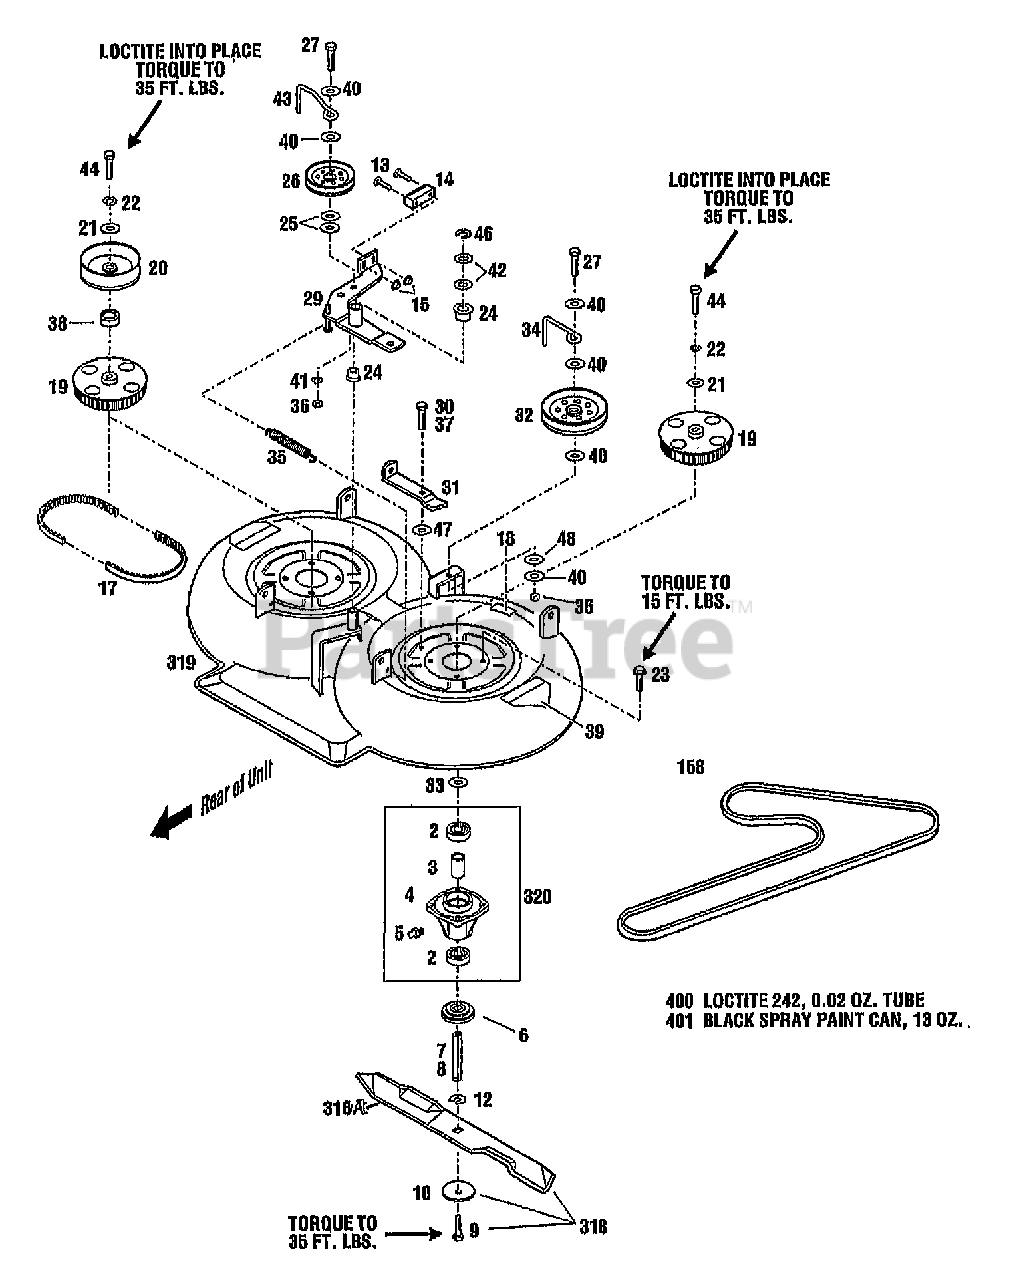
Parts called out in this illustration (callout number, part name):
2	BEARING-BALL
4	HOUSING-SPINDLE
5	FITTING-GREASE 1/4-28X2.00
6	SPACER-BLADE
7	SHAFT-SPINDLE MED. RIGHT SIDE
8	SPINDLE-SHAFT LONG LEFT SIDE
9	SCR-HH 1/2-14X1.00
10	WASHER-BELLEVILLE
12	RING-RETAINING EXT .694 ID
13	SCR-FLAT HEAD
14	PAD-BRAKE
15	NUT-H/LK M10-24 NYLOCK
17	BELT-DRIVE
18	DECAL-CAUTION PINCH POINT
19	COGGED PULLEY, 56T
20	PULLEY-BLADE DRIVE ZP
21	WASHER-1.37X.453X.179 ZP
22	WASHER-LK .438 ZP
23	SCR-HFLK 5/16-18X.75
25	NUT-HFLK 3/8-16 ZP
26	PULLEY-IDLER
27	SCR-HH 3/8-16X2.50
29	ARM-IDLER
30	SCR-HHC 5/16-18X.75 GR 5 ZP
31	BRKT-BELT TENSION ADJ
33	WASHER-THRUST .75 ID
34	GUIDE-BELT
35	SPRING-EXTENSION
36	NUT-HEX 3/8-16 ZP
37	NUT-TOP/LK 5/16-18 ZP
38	SPACER-PULLEY ZP
39	DECAL-OPEI CAUTION
40	WASHER-.75X.406X.092
41	WASHER-LK .375
43	GUIDE-BELT
44	SCR-HH 7/16-14X1.25
46	RING-RETAIN EXT .707 ID
47	WASHER-.312 X .75
48	WASHER-LK .375 PYRAMIDAL
318	KIT-2 BLADE WC MWR 33" (INCL. 9, 10 AND 318)
318A	BLADE-33" MULCHING
319	ASSM-DECK 33" (INCL. 39 & 18)
320	ASSM-MOWER SPINDLE (INCL. 2-5)
400	LOCTITE-242 (.5 ML TUBE)
401	PAINT-BLACK SPRAY
